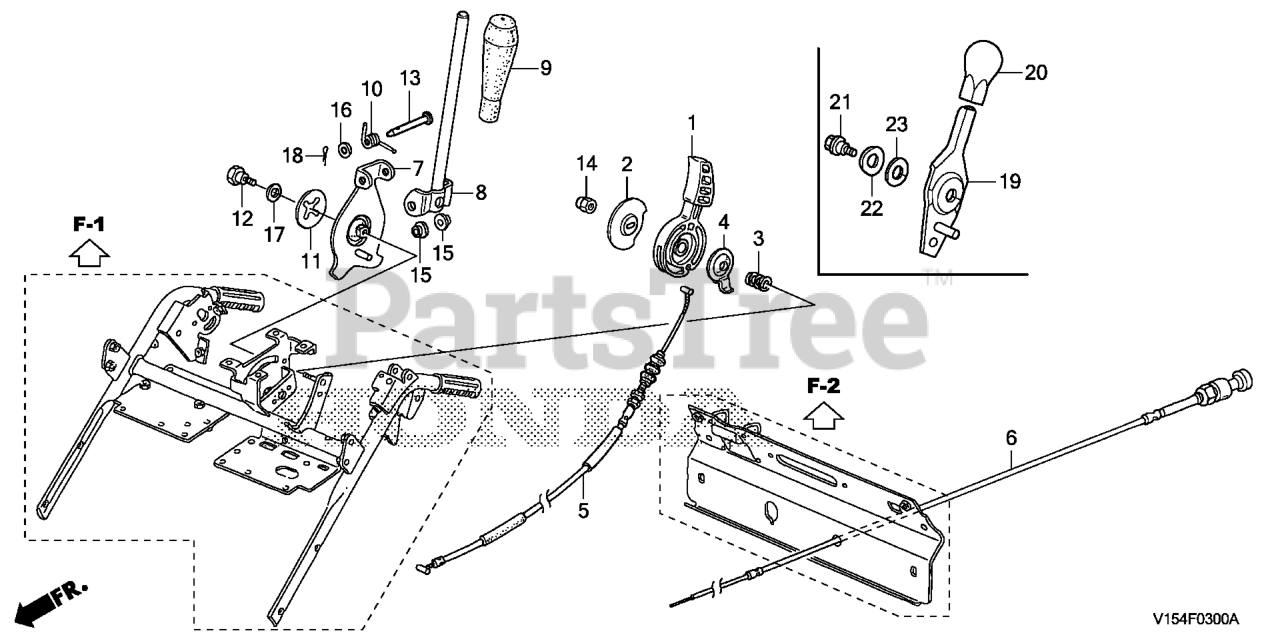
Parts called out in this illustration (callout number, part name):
7	ARM, CHANGE
8	LEVER, CHANGE
9	GRIP, CHANGE LEVER
10	SPRING, CHANGE LEVER RETURN
11	SPRING, ADJUSTING ARM
12	BOLT, THROTTLE LEVER
13	PIN, PILLION STEP
15	BUSH, TURN LEVER
16	WASHER, PLAIN (6MM)
17	WASHER, PLAIN (12MM)
18	PIN, COTTER (1.6X12)
19	LEVER, THROTTLE (COO)
20	KNOB, THROTTLE LEVER (NOT AVAILABLE)
21	BOLT, MAIN STAND LOCK
22	WASHER, WHEEL
23	WASHER, PLAIN (12MM)
